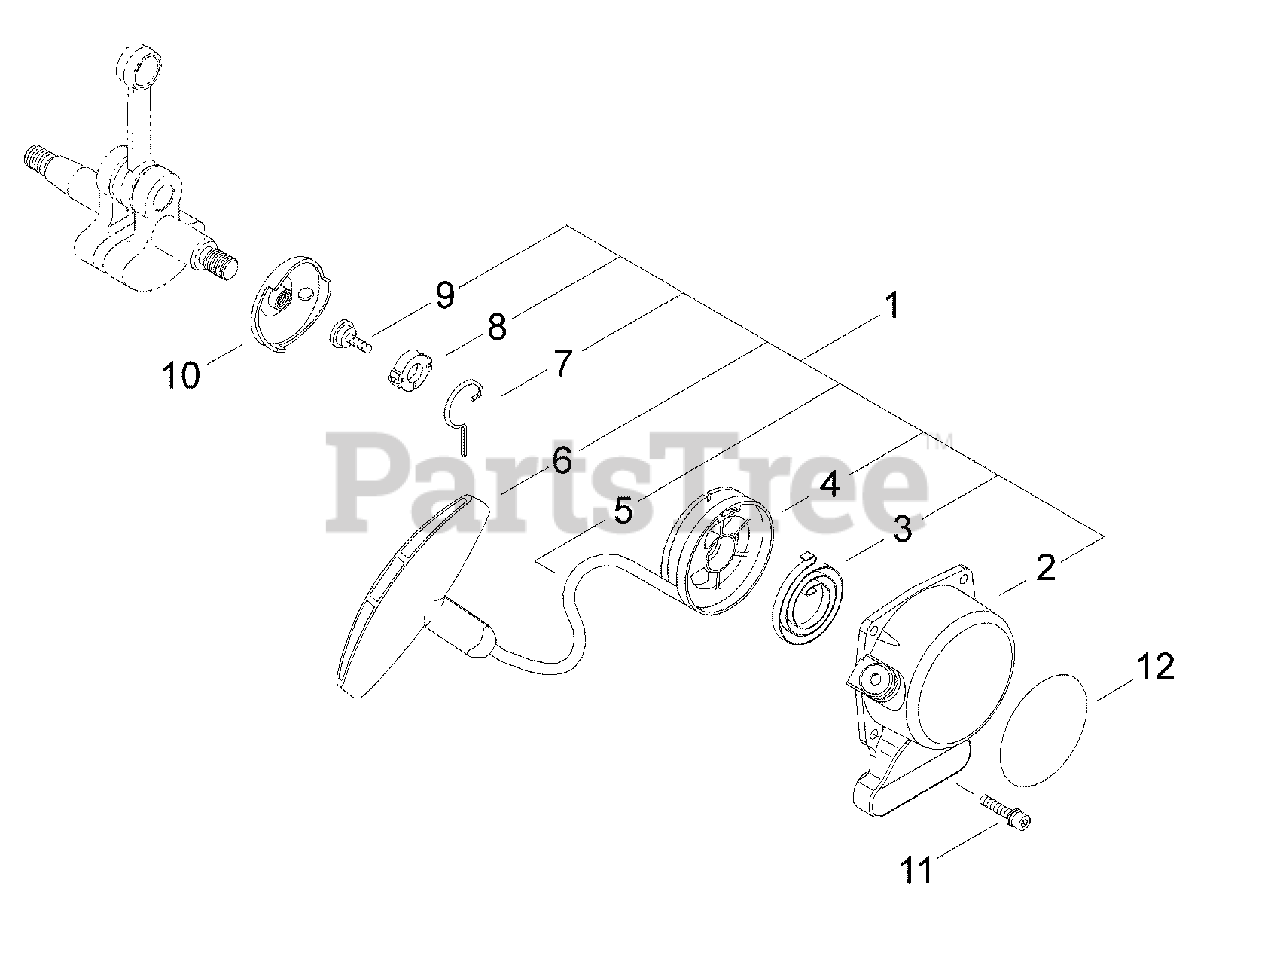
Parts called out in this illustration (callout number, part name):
1	STARTER ASSY, RECOIL
2	CASE, RECOIL STARTER
3	SPRING, RECOIL
4	REEL, ROPE
5	ROPE, STARTER
6	GRIP, STARTER
7	ARM, SWING
8	WASHER 5
9	SCREW 5
10	PULLEY, STARTER
11	BOLT M4×14
12	LABEL, SWISHER E4
